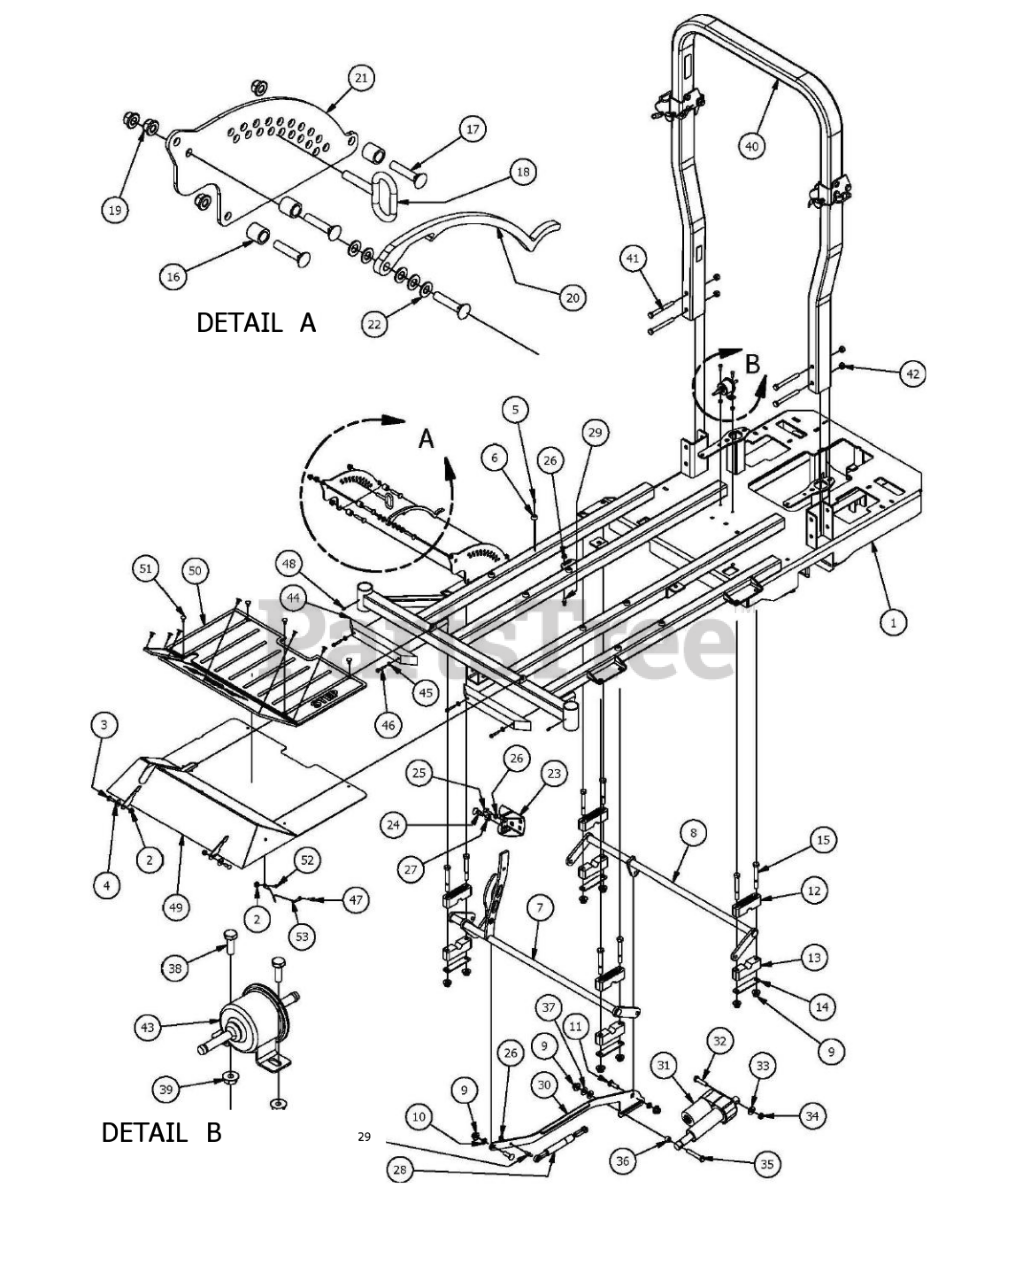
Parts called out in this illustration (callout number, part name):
1	Outlaw Diesel Frame
2	5/16-18 Nylon Flange Nut
3	5/16" x 1" Carriage Bolt
4	.360 ID Plastic Washer
5	#10 x 1/2" Self Tapping Screw
6	Button Bumper
7	2015 Outlaw Act Bar Assembly (Front)
8	2015 Outlaw Act Bar Assembly (Rear)
9	1/2-13 Nylon Flange Nut
10	Bushing- SF-1620-4
11	1/2 x 1-1/2 Carriage Bolt
12	Two Piece Pillow Block (Male)
13	Two Piece Pillow Block (Female)
14	Two Piece Pillow Block Strap
15	1/2" x 4" Bolt (Grade 8)
16	Spacer 3/4 OD x 1/2 ID x 314 Length
17	3/8 x 1 3/4 Carriage Bolt
18	Deck height lever pin
19	3/8" Nylock Flange Nut
20	Outlaw Deck Lever Lock
21	Outlaw Height Indicator Plate (Outer)
22	.390 x .750 x .062 Nylon Washer
23	Outlaw Deck Lift Pedal
25	5/16-18 x1 Thumb Screw Zinc
26	5/16" Flange Nut
27	1/2" Hex Nut
28	250lb Gas Spring
29	10mm Damper Ball Stud-Steering
30	Outlaw Linkage Bar Susp Frame
32	1/2-13x2 Grade 8 Hex Bolt
33	1/2" Washer (Grade 8)
34	1/2" Nylock Nut (1/2 Jam)
35	1/2" x 3" Hex Bolt
36	1/2 x 1/2 Spacer
37	.505 Nylon Spacer
38	1/4" x 3/4" Hex Bolt
39	1/4-20 Hex Flange Nuts Zinc w/Serrations
40	2014 & Newer Diesel 2x3 Folding ROPS
41	1/2" x 4 1/2" Bolt
42	1/2" Center Lock Nut
43	Electric Fuel Pump
44	14" Rubber Bumper
45	1/4" Flat Washer
46	1/4" x 1 1/2" Self Tapping Screw
47	1/4 x 1 Hex Head tek screw
48	1/4" Press in Grease Fitting
49	Compact Diesel Floorboard
50	Foot Assist Floor Mat
51	Ratchet Fastener
52	1/4" x 5/8" BS C/S 18-8 SS
53	Floor board Cable W/ Swivel Ends
